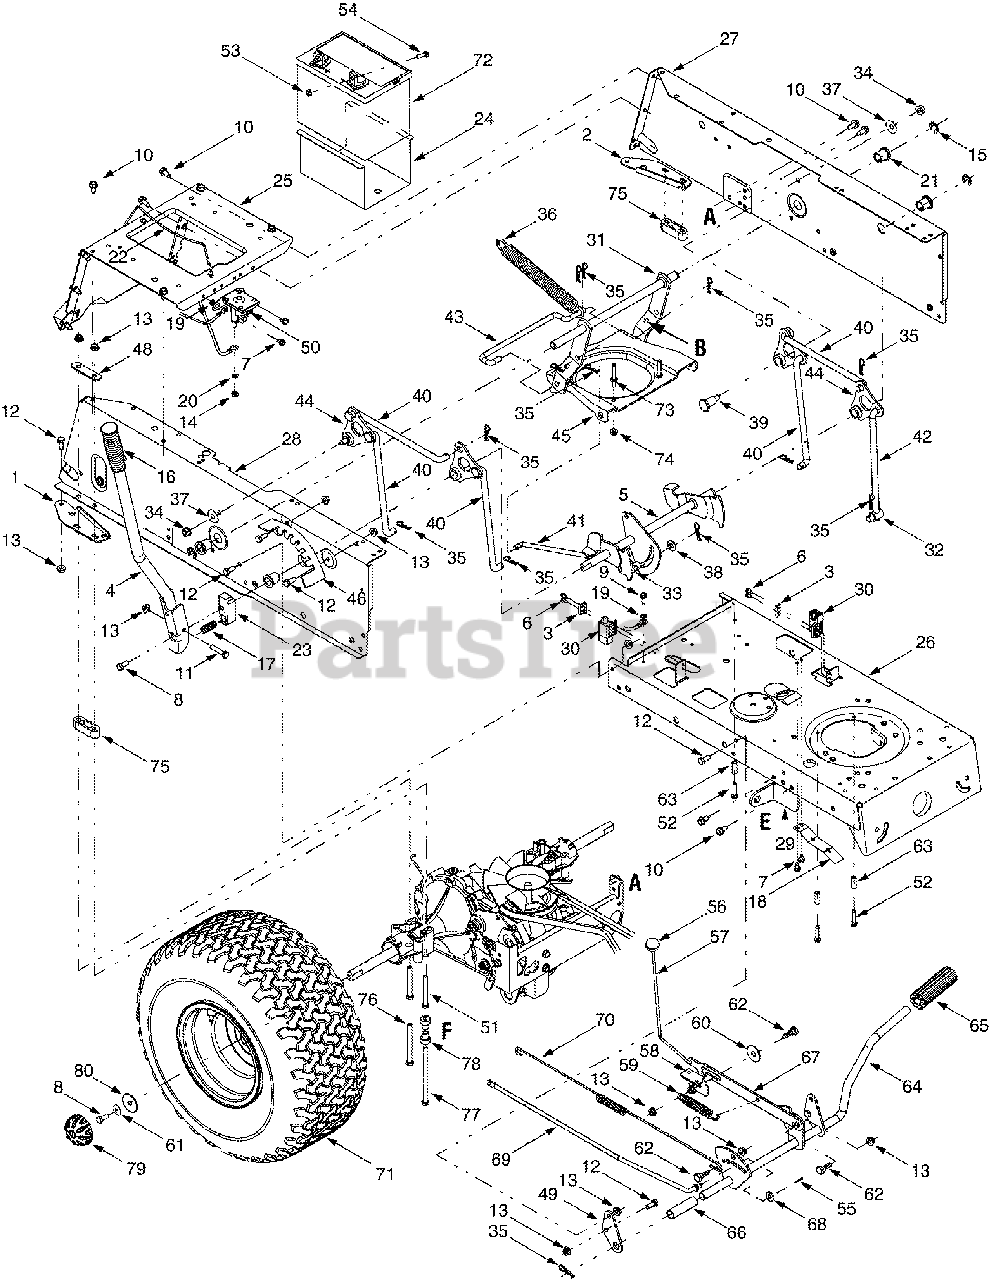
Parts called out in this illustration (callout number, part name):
6	Self-tapping Screw, #10-16 x .5
7	Self-tapping Screw, 1/4-20 x .5
8	Hex Cap Screw, 5/16-24 x .75
9	Self-tapping Screw, 1/4-20 x .75
10	Self-tapping Screw, 5/16-12 x .75
11	Hex Cap Screw, 5/16-18 x 1.5
12	Hex Screw, 5/16-18 x .75
13	Flange Lock Nut, 5/16-18
14	Hex Nut, 1/4-20
15	E-Ring, .625 Dia Shaft
16	Handle Grip
17	Compression Spring, .55 x 1.37
18	Switch Actuator Spring
19	External Lock Washer, 1/4
20	Lock Washer, 1/4
21	Flange Bearing, .632 ID
22	Battery Hold-down Rod
23	Lift Shaft Connector
33	Ferrule, 3/8-24 x .375
34	Flange Lock Nut, 3/8-16
35	Internal Cotter Pin, .080 x 1.56
36	Extension Spring, 1.07 x 9.52
37	Bell Washer, .389 x 1.12 x .030
38	Flat Washer, .385 x .87 x .060
39	Shoulder Bolt, 3/8-16 x .62 x .92
40	Deck Hanger Link
41	Deck Disengagement Rod
42	Deck Hanger Link
43	Rear Stabilizer Rod
44	Lift Link
51	Hex Cap Screw, 5/16-18 x 2.75
52	Self-tapping Screw, 1/4-20 x 1.25
53	Hex Sems Nut, 1/4-20
54	Hex Screw,1/4-20 x .75
55	Cotter Pin, 1.0
56	Ball Knob
57	Brake Lockout Rod
58	Bracket
59	Extension Spring, 4.31
60	Flat Washer, .442 x 1.38 x .060
61	Bell Washer, .34 x .872 x .060
62	Shoulder Screw, .437 x .286
63	Spacer, .260 x .372 x 1.030
66	Spacer, .640 x .76 x 2.63
67	Brake Lockout Bracket
68	Flat Washer, .344 x .750 x .120
69	Brake Rod
70	Extension Spring, 22.16
72	Battery, 270 CCA
72	Battery, 235 CCA
73	Flange Lock Nut, 1/4-20
74	Belt Guard Pin, 1/4-20
75	Spacer
76	Hex Cap Screw, 5/16-18 x 3.25
77	Hex Cap Screw, 5/16-18 x 5.25
78	Shoulder Spacer
79	Deluxe Hub Cap
80	Flat Washer, .350 x 1.59 x .062
